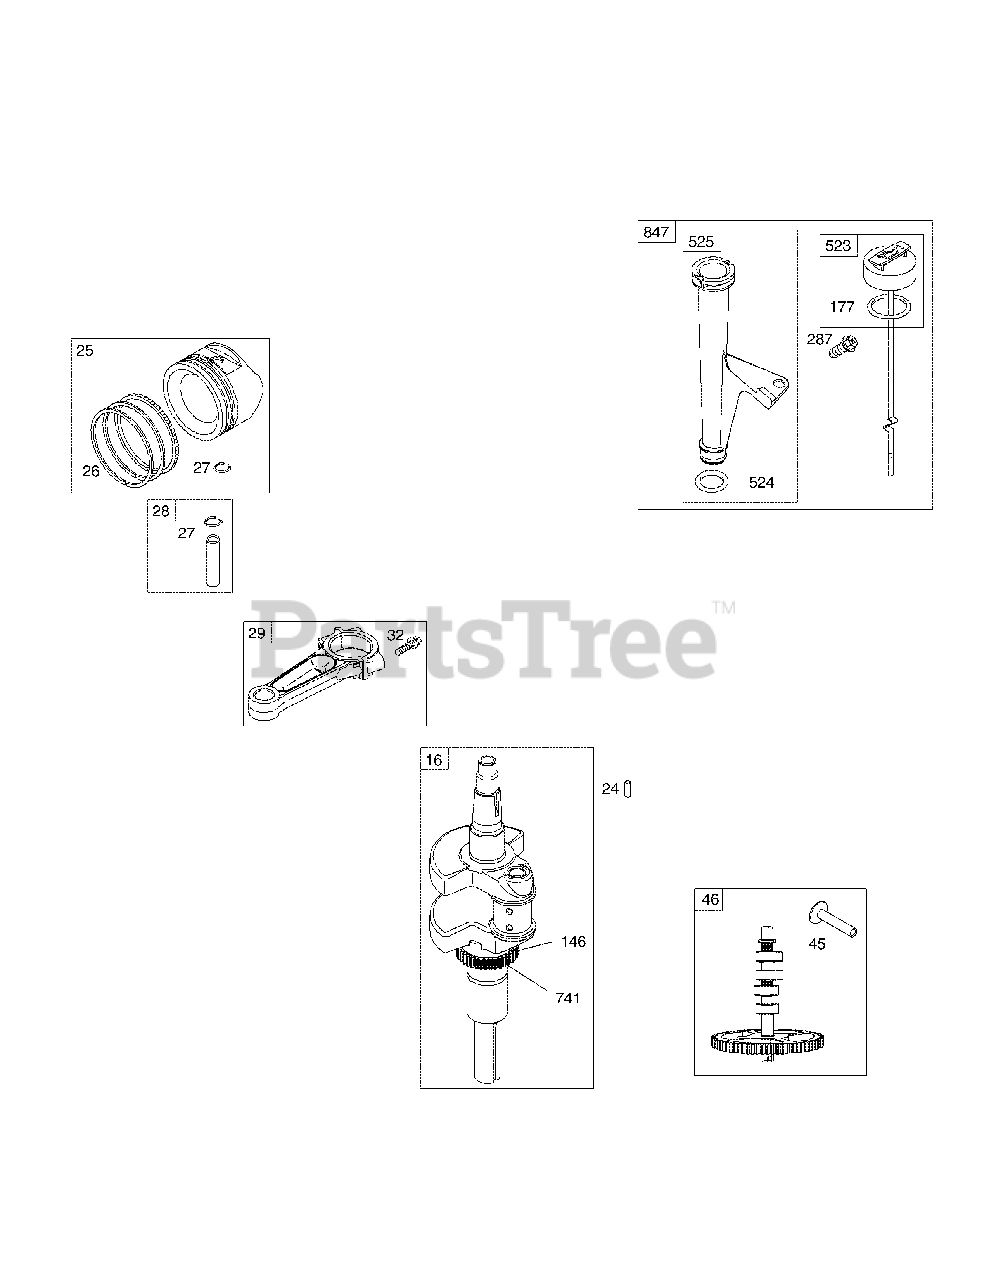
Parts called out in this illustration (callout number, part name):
1	Cylinder Assembly
2	Kit-Bushing/Seal (Magneto Side)
3	Oil Seal (Magneto Side)
4	EngineSump
5	Cylinder Head (Cylinder #1)
5A	Cylinder Head (Cylinder #2)
7	Cylinder Head Gasket
8	Breather Assembly
9	Breather Gasket
10	Screw (Breather Assembly)
11	Breather Tube
12	Crankcase Gasket
13	Screw (Cylinder Head)
15	Oil Drain Plug
16	Crankshaft
20	Oil Seal (PTO Side)
22	Screw (Crankcase Cover/Sump)
23	Flywheel
24	Flywheel Key
25	Piston Assembly (Standard)
25	Piston Assembly (.020" Oversize)
26	Ring Set (Standard)
26	Ring Set (.020" Oversize)
27	Piston Pin Lock
28	Piston Pin
29	Connecting Rod
32	Screw (Connecting Rod)
33	Exhaust Valve
34	Intake Valve
35	Valve Spring (Intake)
36	Valve Spring (Exhaust)
40	Valve Retainer
42	Valve Keeper
45	Valve Tappet
48	Short Block
50	Intake Manifold
51	Intake Gasket
51A	Intake Gasket
53	Stud (Carburetor)
54	Screw (Intake Manifold)
73	Rotating Screen
74	Screw (Rotating Screen)
75	Washer (Flywheel)
95	Screw (Throttle Valve)
98	Idle Speed Kit
104	Float Hinge Pin
105	Float Needle Valve
108	Choke Valve
117	Main Jet (Standard) (Left Jet)
117A	Main Jet (Standard) (Right Jet)
118	Main Jet (High Altitude) (Left Jet)
118A	Main Jet (High Altitude) (Right Jet)
121	Carburetor Overhaul Kit
125	Carburetor
130	Throttle Valve
131	Throttle Shaft Kit
133	Carburetor Float
135	Fuel Transfer Tube
137	Float Bowl Gasket
141	Choke Shaft Kit
142	Carburetor Nozzle
146	Timing Key
150	Nozzle Gasket
163	Air Cleaner Gasket
165	Nut (Ring Gear)
177	O-Ring Seal (Dipstick)
187	Fuel Line (Cut to Required Length)
188	Screw (Control Bracket)
192	Rocker Arm Adjuster
197	Screw (Back Plate)
209	Governor Spring (Yellow/Black)
211	Governed Idle Spring (Orange)
212	Throttle Link
216	Choke Link
217	Choke Return Spring
219	Governor Gear
220	Washer (Governor Gear)
221	Governor Cup
222	Control Bracket
227	Governor Control Lever
231	Screw (Choke Valve)
239	Oil Pressure Switch
240	Fuel Filter
250	Breather Retainer
252	Oil Collector
265	Casing Clamp
267	Screw (Casing Clamp)
276	Sealing Washer (Fuel Solenoid)
278	Washer (Governor Control Lever)
287	Screw (Dipstick Tube)
304	Blower Housing
305	Screw (Blower Housing)
305A	Screw (Blower Housing to Intake Elbow)
306	Cylinder Shield (Cylinder #2)
307	Screw (Cylinder Shield) (1.4-20 x 2.3)
309	Starter Motor
310	Screw (Starter Motor)
332	Nut (Flywheel)
333	Magneto Armature
334	Screw (Magneto Armature)
337	Spark Plug
358	Engine Gasket Set
385	Screw (Fuel Pump)
387	Fuel Pump
404	Washer (Governor Crank)
415	Plug (Oil Pressure Switch)
418	Carburetor Plate
431	Intake Elbow
445	Air Cleaner Cartridge Filter
447	Screw (Air Guide Cover) 10-24 x 7.16)
447A	Screw (Air Guide Cover)
467	Air Cleaner Knob
474	Alternator
501	Regulator
503	Starter Strap
505	Nut (Governor Control Lever)
510	Starter Drive
513	Drive Clutch
523	Dipstick
524	Dipstick Tube Seal
525	Dipstick Tube
526	Screw (Regulator)
544	Starter Armature
552	Governor Crank Bushing
552A	Governor Crank Bushing
562	Screw (Governor Control Lever)
573	Back Plate
579	Nut (Starter Cable)
601	Hose Clamp (Black)
601A	Hose Clamp (Green)
615	Governor Shaft Retainer
616	Governor Crank
617	O-Ring Seal (Intake Manifold) (Red)
628	Screw (Fuel Pump Bracket)
633	Choke Seal/Throttle Shaft
635	Spark Plug Boot
654	Nut (Carburetor)
668	Spacer (Rotating Screen)
668A	Spacer (Rotating Screen)
672	Carburetor Plate Gasket
691	Governor Shaft Seal
695	Screw (Ring Gear)
697	Screw (Drive Cap)
718	Locating Pin
741	Timing Gear
742	E-Ring Retainer (Governor Crank)
750	Screw (Oil Pump Cover)
783	Pinion Gear
788	Fuel Pump Bracket
789	Wiring Harness
798	Screw (Rocker Arm)
803	Starter Housing
847	Dipstick/Tube Assembly
851	Spark Plug Terminal
865	Air Guide Cover (Cylinder #1)
865A	Air Guide Cover (Valley)
868	Valve Seat
877	Alternator Wire/Connector
877A	Alternator Wire/Connector
883	Exhaust Gasket
914	Screw (Rocker Cover)
918	Vacuum Hose
943	O-Ring Seal (Oil Pump Cover)
947	Fuel Solenoid
965	Oil Pump Cover
967	Pre-Cleaner Filter
968	Air Cleaner Cover
975	Float Bowl
987	Throttle Shaft Seal
1005	Flywheel Fan
1013	Oil Filter Nipple
1017	Oil Pump Screen
1022	Rocker Cover Gasket
1023	Rocker Cover (Cylinder #1)
1023A	Rocker Cover (Cylinder #2)
1026	Push Rod (Exhaust)
1026A	Push Rod (Intake)
1027	Oil Filter
1029	Rocker Arm
1036	Emissions Label
1040	Trim Plate
1051	Retaining Ring (Starter Drive)
1059	Screw/Washer Kit (Alternator)
1070	Screw (Flywheel Fan)
1090	Brush Retainer
1095	Valve Gasket Set
1100	Rocker Arm Pivot
1119	Screw (Alternator)
1124	O-Ring Seal (Fuel Transfer Tube)
1124A	O-Ring Seal (Fuel Transfer Tube)
1126	Screw (Fuel Transfer Tube)
1127	Screw (Fuel Bowl)
1128	Screw (Carburetor Nozzle)
1169	Screw (Carburetor Plate)
1329	Replacement Engine
